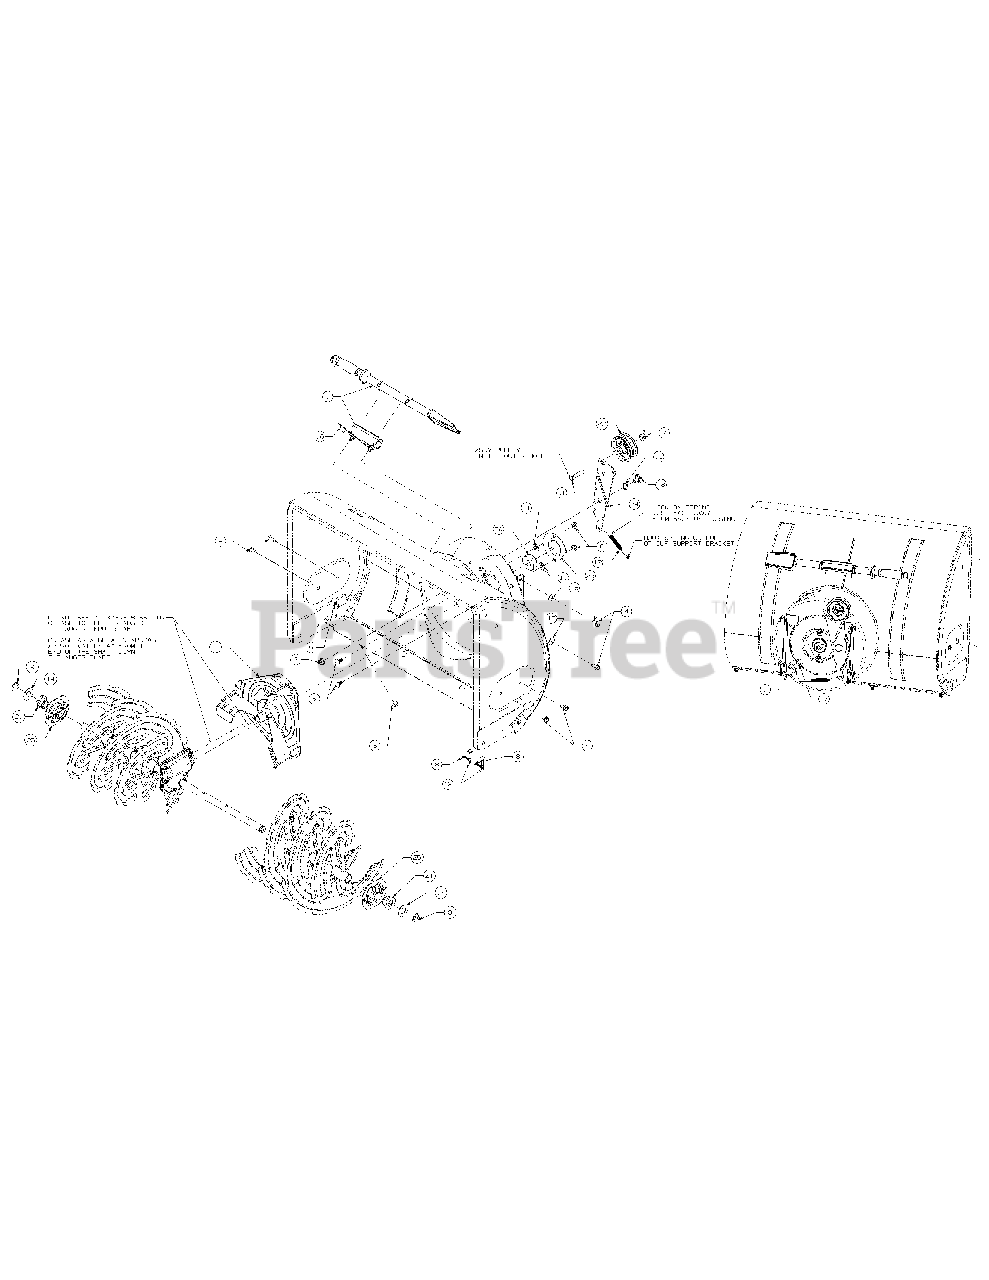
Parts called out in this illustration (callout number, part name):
1	Tool-Cleanout
1	Clip-Tool Mtg
2	Impellor
3	Screw-Hex 3/8-16 X
5	Carriage Bolt 5/16-18 X .75
6	Nut-Flglk 5/16-18
7	Nut-Flange Lk.Nylon
8	Pin-Cotter
9	Ring-E
10	Tie-Cable 7"
11	Nut-Push On
12	Spring-Extension
13	Washer-Wave .660 I
14	Washer-Fl-.760Id X
15	Washer-Bell .337 X
16	Grease
17	Screw-Shld .498 Di
18	Screw-Shld .625
19	Pin-Shear .25
20	Flange Bearing .
21	Bearing-Flange Hex
22	Pulley:Idler:Flat
23	Housing-Bearing
25	Housing-Hex Brg
